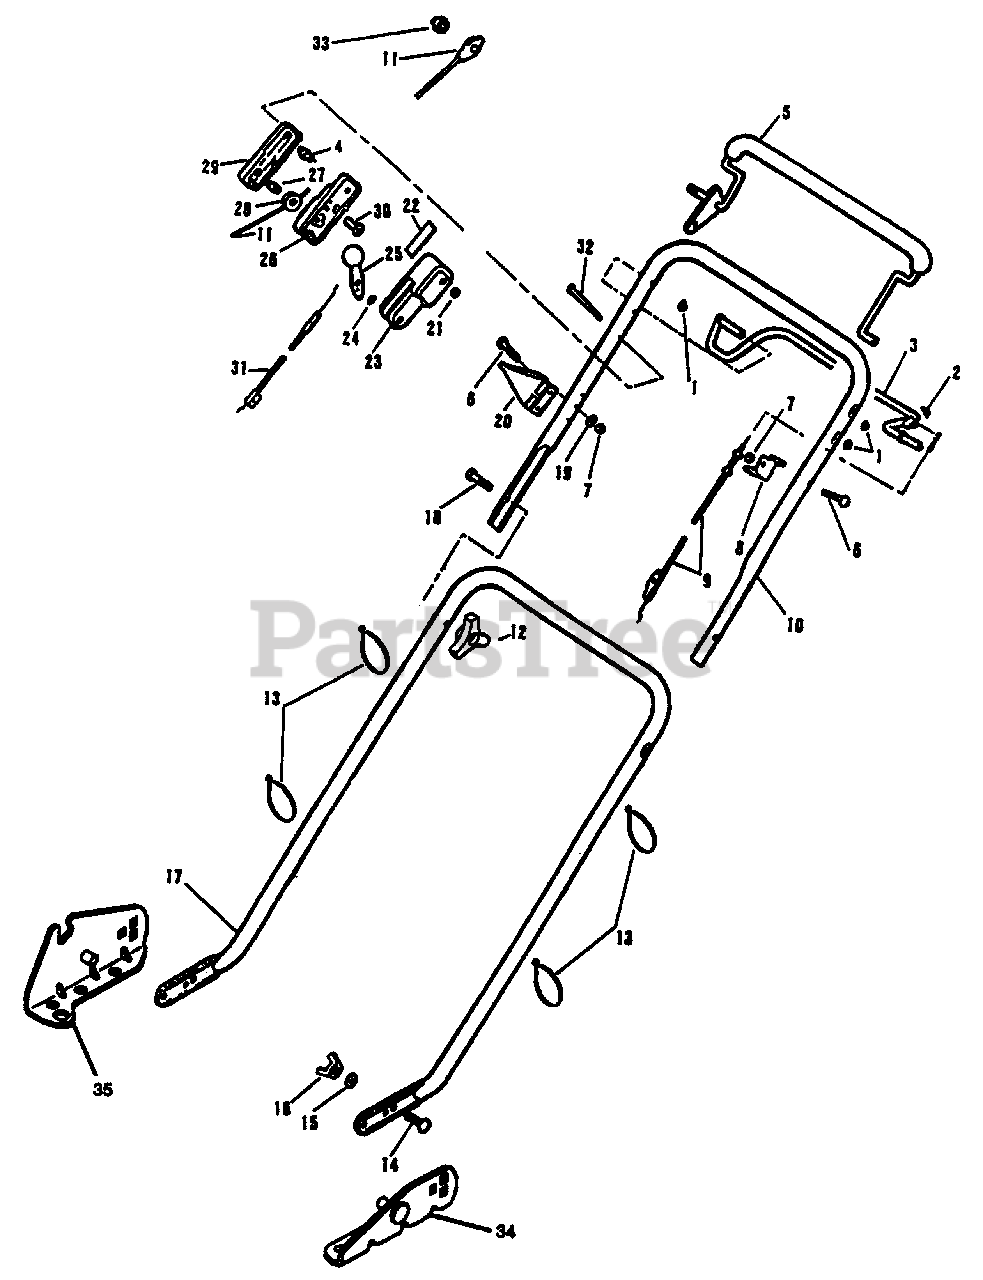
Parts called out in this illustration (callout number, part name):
1	Palnut (Self Propelled)
2	Palnut (Self Propelled)
3	Self Propel Bail (Self Propelled)
4	Column
5	Control Lever Assembly
6	Screw (Self Propelled)
7	Nut (Self Propelled)
8	Conduit Anchor (Self Propelled)
9	Control Cable (Self Propelled)
10	Handle-Top
11	Engine Control Cable
12	Handle Knob
13	Tie Strap (Self Propelled)
14	Bolt-Handle to Handle Bracket
15	Washer
16	Wing Nut
17	Handle-Lower
18	Screw
19	Washer
20	Rope Guide Assembly
21	Nut
22	Decal-Throttle Control
23	Throttle Case-Inner
24	Washer
25	Lever & Knob Assembly
26	Throttle Case-Center
27	Pin
28	Pulley
29	Control Case-Outer
30	Screw
31	Throttle Cable
32	Screw
33	Acorn Nut
34	Bracket-Handle L.H. (Push)
35	Bracket-Handle R.H. (Push)
